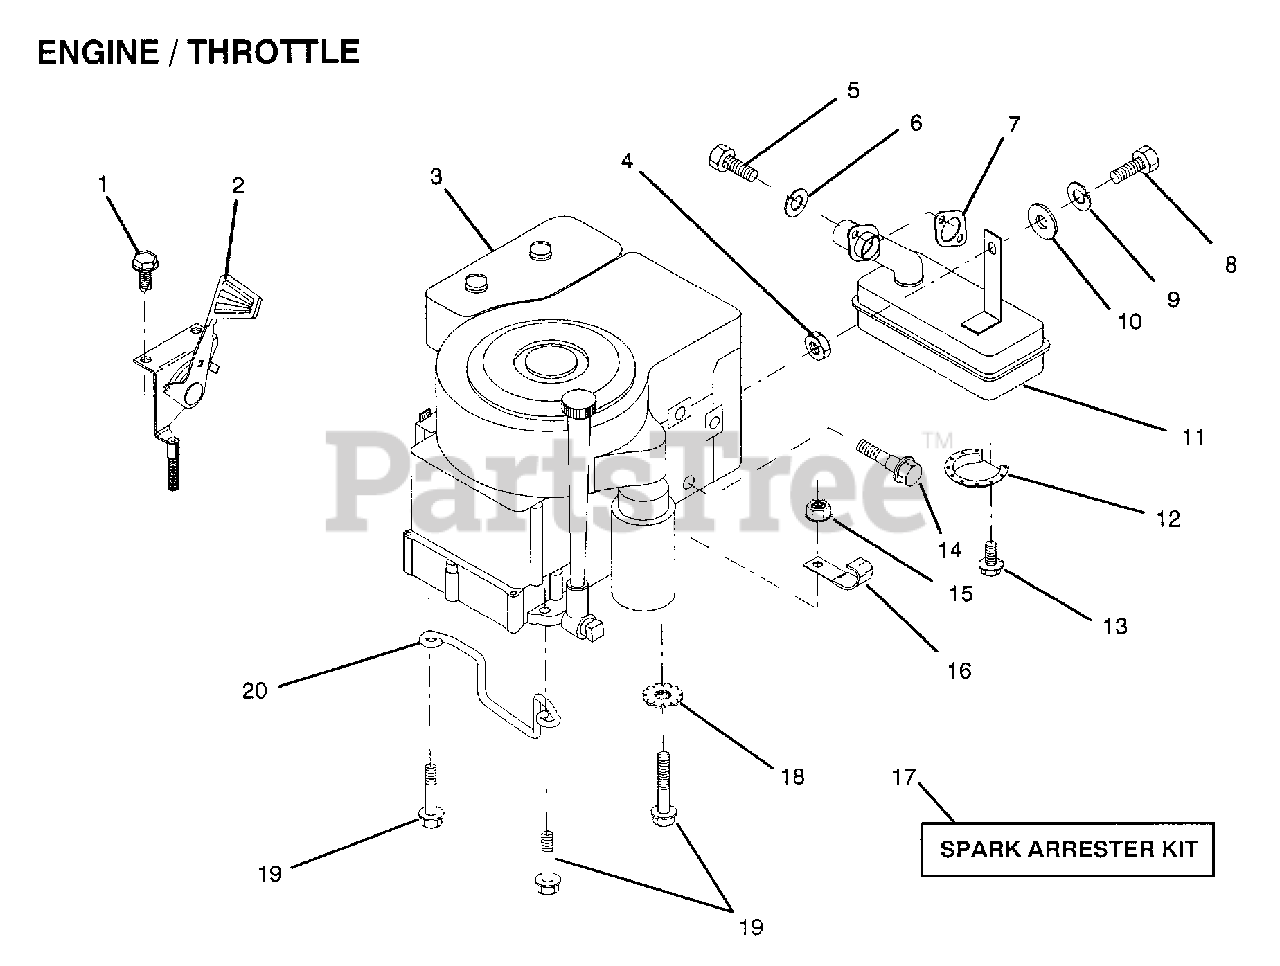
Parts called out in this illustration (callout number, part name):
1	SCREW
2	CONT.THROTTLE
4	NUT.HEX.5/16-18
5	SCREW
6	LOCKWASHER
8	BOLT
9	LOCKWASHER
11	MUFFLER
12	DEFLECTOR.222573
14	SHOULDER BOLT T
15	NUT
16	CLIP T
18	LOCKWASHER
19	SCREW LT
20	"KEEPER,DR BELT GR"
